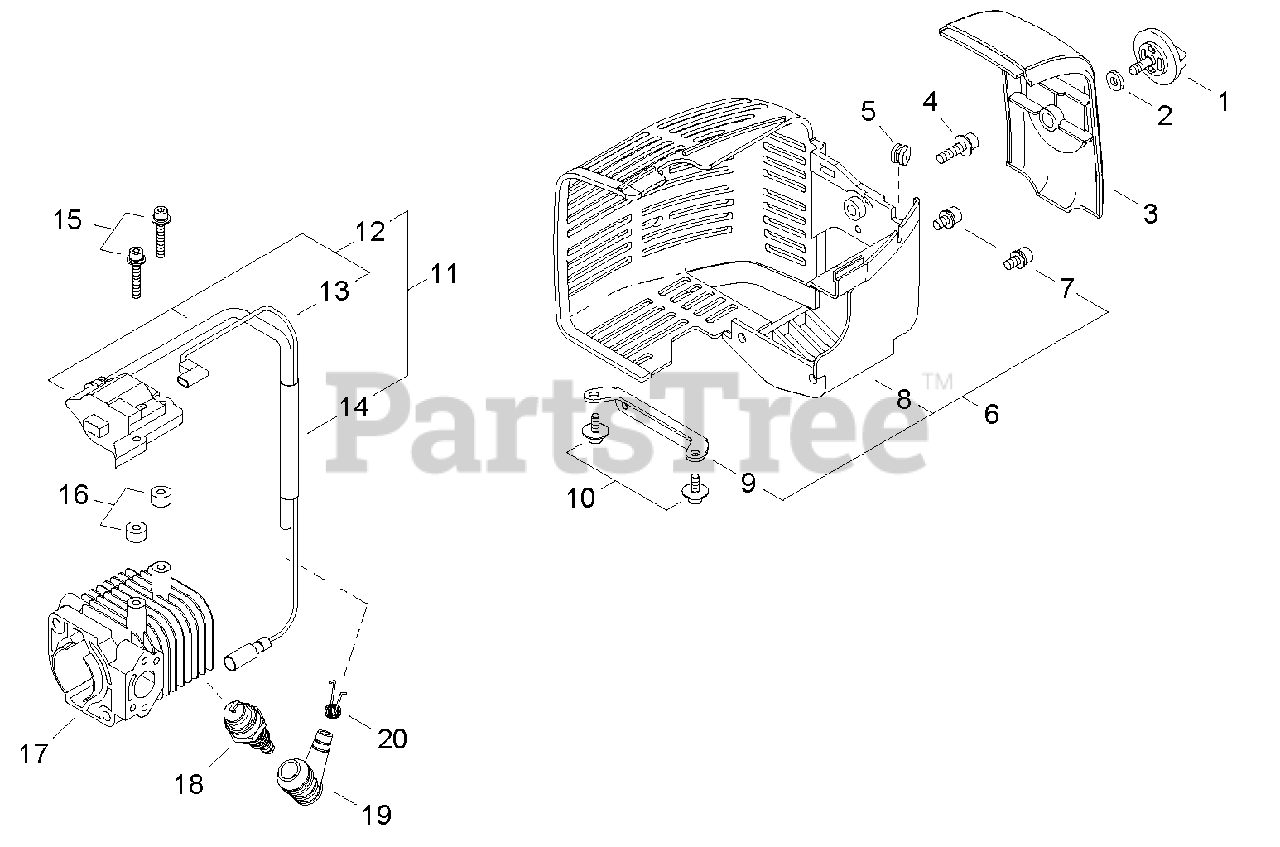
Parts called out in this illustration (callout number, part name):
1	THUMBSCREW
2	WASHER - VINYL
3	COVER, SPARK PLUG
4	SCREW - 5X20
5	GROMMET
6	ENGINE COVER KIT
7	SCREW - 5
8	COVER, ENGINE
9	BRACKET, ENGINE COVER
10	BOLT - 4
11	IGNITION COIL ASSY
12	IGNITION COIL ASSY
13	LEAD - IGNITION
14	TUBE, INSULATOR
15	SCREW - 4X26
16	INSULATOR
17	CYLINDER
18	SPARK PLUG -- BPMR-6A
19	CAP, SPARK PLUG
20	TERMINAL, SPARK PLUG CAP
